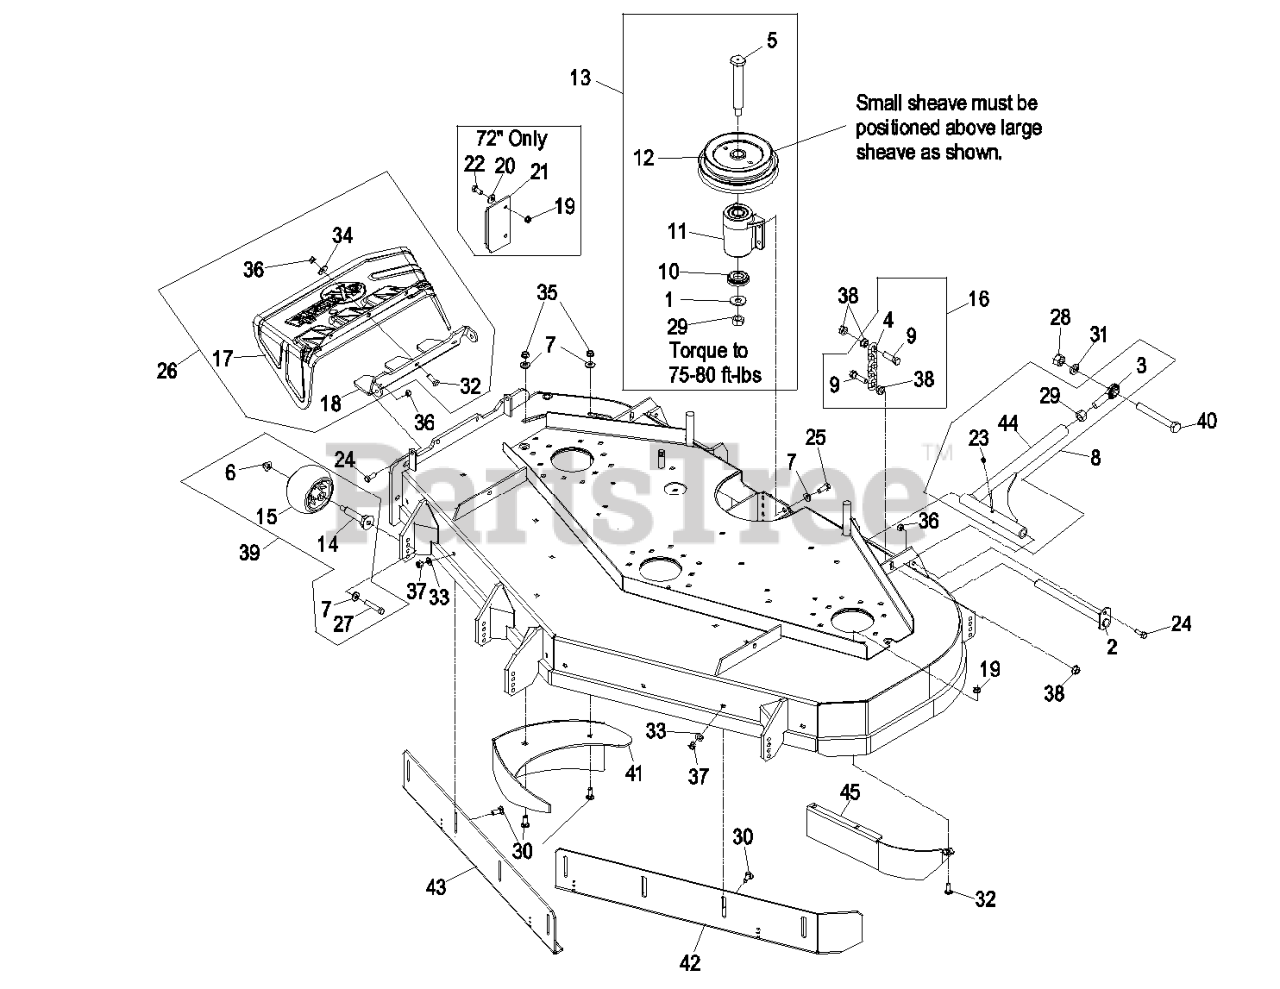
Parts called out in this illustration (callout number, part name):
1	WASHER-SPRING
2	PIN-STRUT
3	BALLJOINT-SPHERICAL
4	CHAIN-LIFT, DECK
5	JACKSHAFT
6	Nut-Nyloc 3/8-16 Flg
7	WASHER-BELLEVILLE
8	STRUT ASM
9	SCREW-HH
10	SPACER-GUARD, BOTTOM
11	KIT, JACKSHAFT ASSY
12	SHEAVE, JACKSHAFT DOUBLE
13	KIT,JACKSHAFT 60/72-3750
15	ROLLER-SCALP, ANTI
16	DECK CHAIN ASM
17	CHUTE,DISCHARGE LZ
18	HINGE,DISCHARGE CHUTE
20	WASHER-FLAT
21	DEFLECTOR,DISCHARGE
22	SCREW-HH
23	FITTING-GREASE
24	SCREW-HH
25	SCREW-HH
26	ASM, DISCHARGE CHUTE
27	SCREW-HH
28	NUT-HEX
29	NUT-HEX
30	SCREW-CARR
31	WASHER-LOCK
32	SCREW-CARR
33	WASHER-FLAT
34	WASHER-FLAT
35	NUT-HHF, WHIZ
36	NUT-LOCK, NI
37	NUT-LOCK, NI
40	SCREW-HH
41	WLD,DOGLEG 605
42	WLD,BAFFLE FRT ADJ LH 605
43	WLD,BAFFLE FRT ADJ RH 605
45	BAFFLE,SCROLL 605
